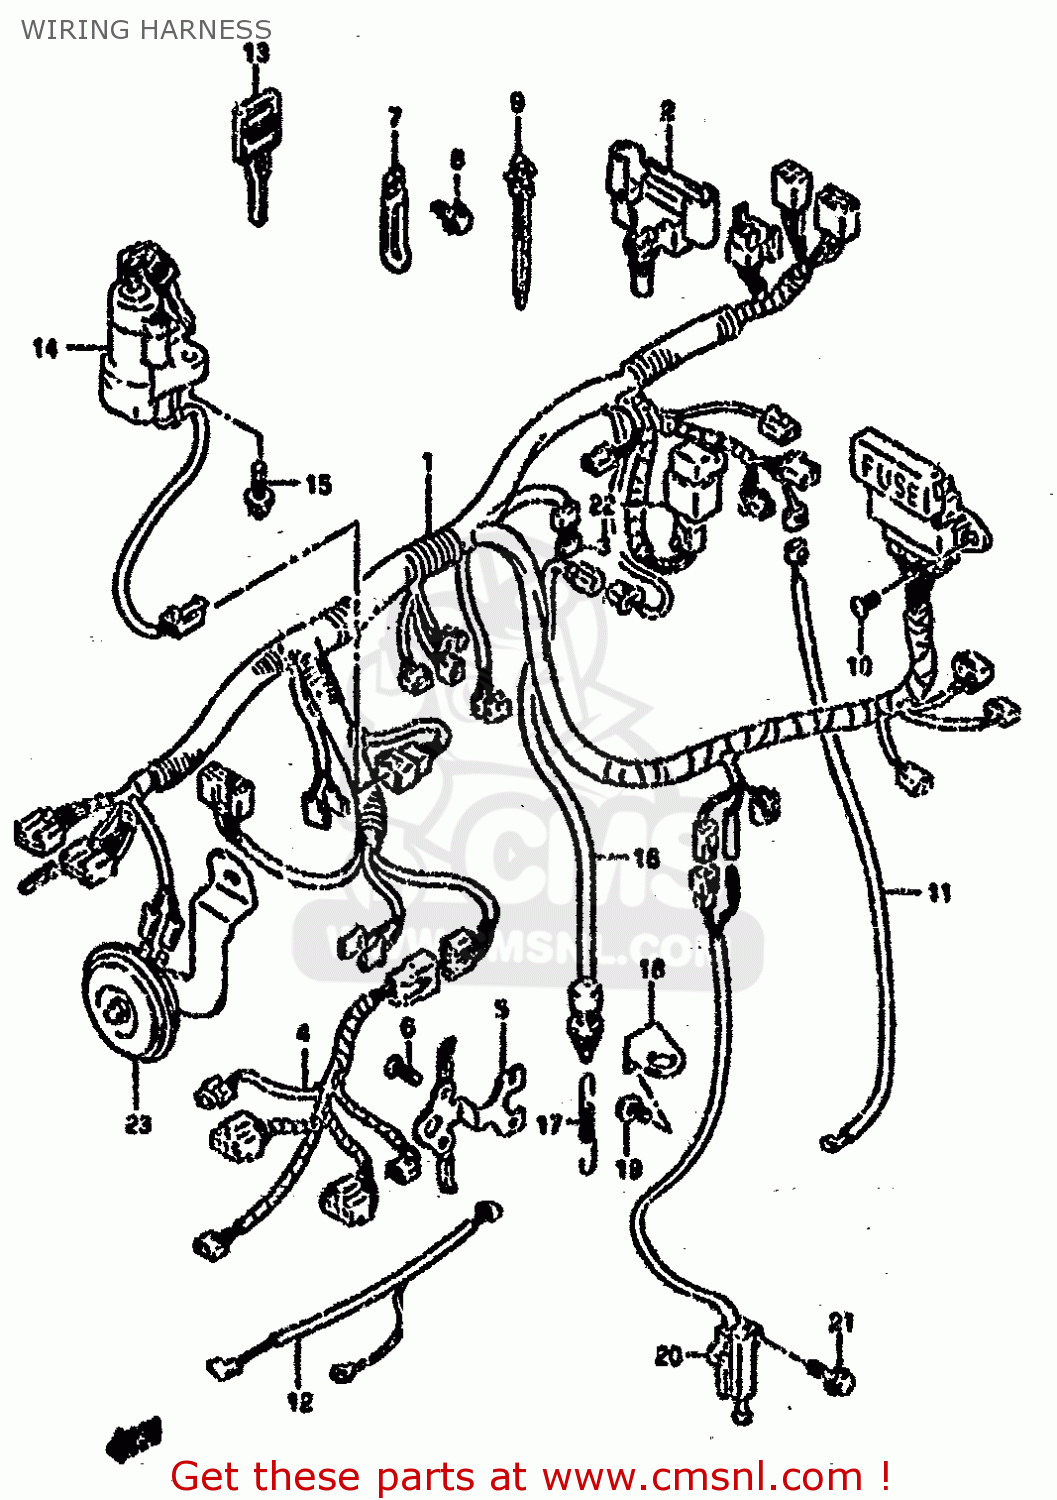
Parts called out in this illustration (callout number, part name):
1	HARNESS,WIRING
2	CAP,STARTER RELAY
3	DIODE(STANLEY DE8804)
4	HARNESS,WIRING NO.2
5	HOLDER COMP,COUPLER
6	SCREW 5X8
7	CLAMP
8	BOLT
9	CLAMP L:165
10	SCREW 6X12
11	WIRE,WATER TEMPERATURE GAUGE
12	WIRE,OIL PRESSURE SWITCH LEAD
13	KEY,BLANK
14	LOCK ASSEMBLY,STEERING
15	BOLT M8X20
16	SWITCH ASSY,STOP LAMP
17	SPRING
18	BRACKET,STOP LAMP SWITCH
19	SCREW(6X12)
20	SWITCH ASSEMBLY,SIDE STAND
21	BOLT
22	RELAY ASSEMBLY
23	HORN ASSEMBLY,LOW PITCH
